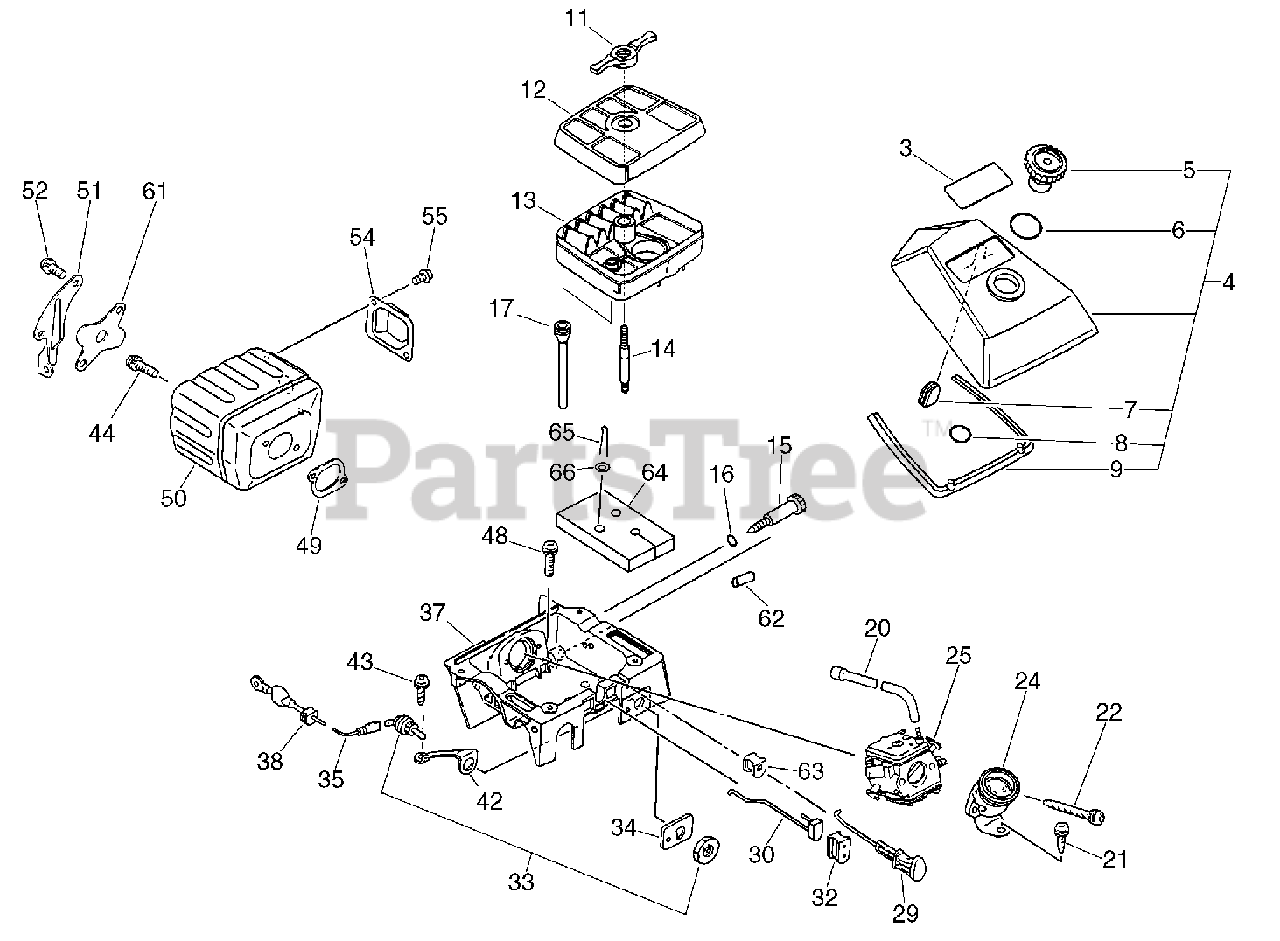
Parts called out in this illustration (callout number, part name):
3	LABEL - MODEL
4	AIR FILTER COVER ASSY
5	THUMBNUT
6	O-RING - 21
8	O-RING - 11
9	SEAL
11	HOLDER, ELEMENT
12	FILTER, AIR
13	FILTER, AIR
14	POST
15	SCREW, IDLE ADJUST
16	O-RING - 7
20	PIPE - IMPULSE
21	SCREW - 5X14
22	SCREW - 5X53
24	ADAPTOR, INTAKE
25	CARBURETOR
29	ROD, CHOKE
30	ROD, THROTTLE
32	GUIDE, THROTTLE ROD
33	IGNITION SWITCH ASSY
34	LABEL - STOP
35	LEAD - GROUND
37	CASE, CARBURETOR
42	TERMINAL - GROUND
43	SCREW - 4X10
44	SCREW - 5X20
48	SCREW - 5X20
49	GASKET, EXHAUST
50	MUFFLER
51	BRACKET, MUFFLER
52	SCREW - 5X14
54	GUIDE, EXHAUST
55	SCREW - 4X10
61	COVER, MUFFLER
63	GROMMET
65	PIN, SPLIT - 3X18
